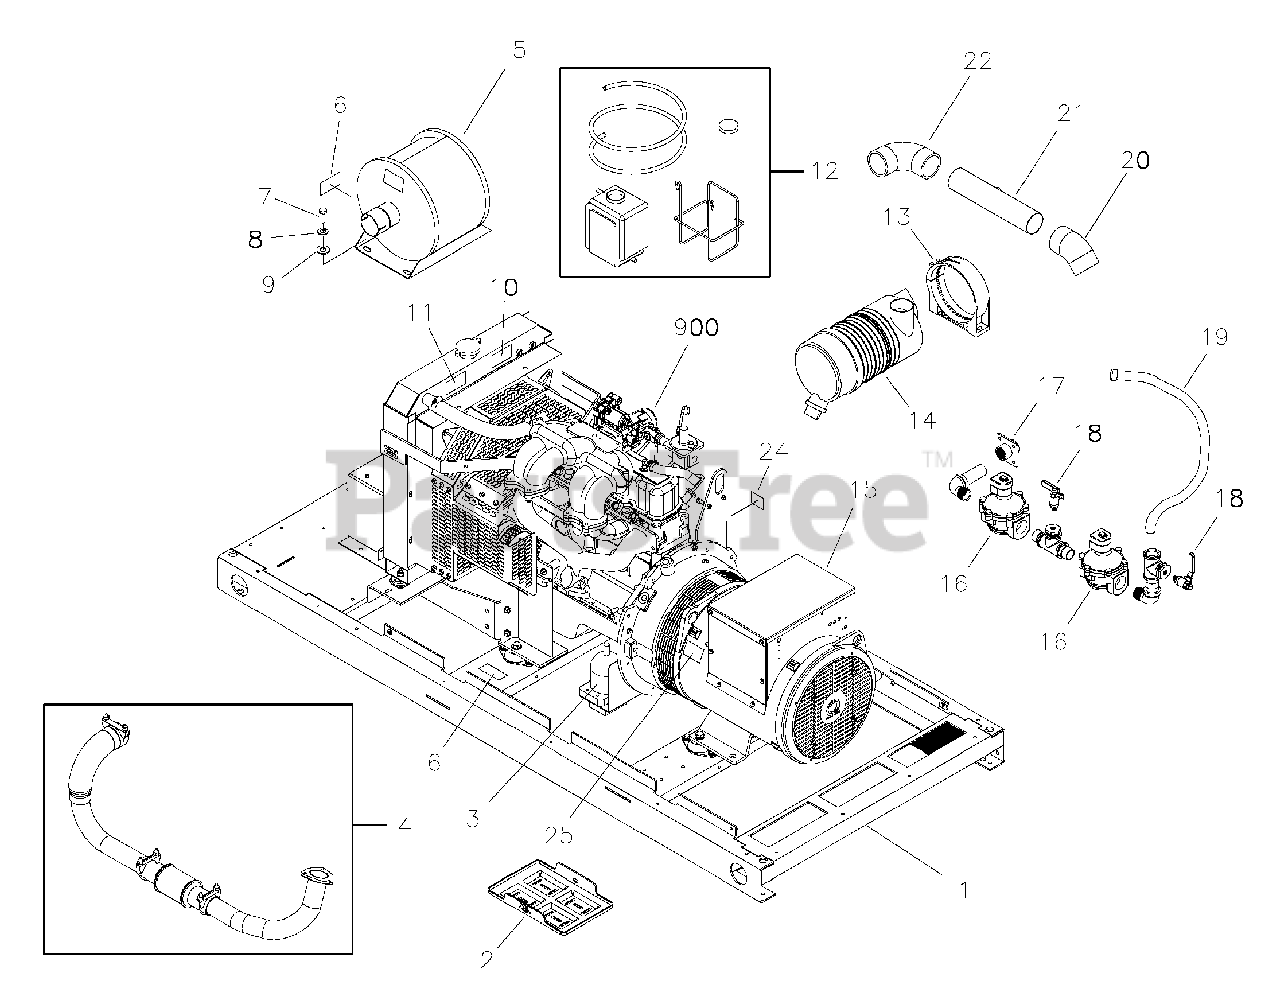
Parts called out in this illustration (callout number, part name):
1	BASE
3	ASSEMBLY, Heater, Tank
5	SILENCER, Muffler
6	DECAL, Burn Hazard
7	*CAPSCREW, Hex Head, 5/16-18 x 1
8	*WASHER, Lock, 5/16 - M8
9	*WASHER, Flat, 5/16 - M8
10	DECAL, Warning Hot Coolant
11	DECAL, Warning Moving Parts
12	KIT, Bottle Overflow
13	CLAMP, Air Cleaner
15	ASSEMBLY, Alternator
16	ASSEMBLY, Fuel Valve
17	COUPLER, Fuel System
18	VALVE, Ball 1/4
19	ASSEMBLY, Hose, Fuel
21	TUBE, Inlet, Air
24	DECAL, Oil Drain
25	DECAL, Explosion Hazard
900	** ENGINE
